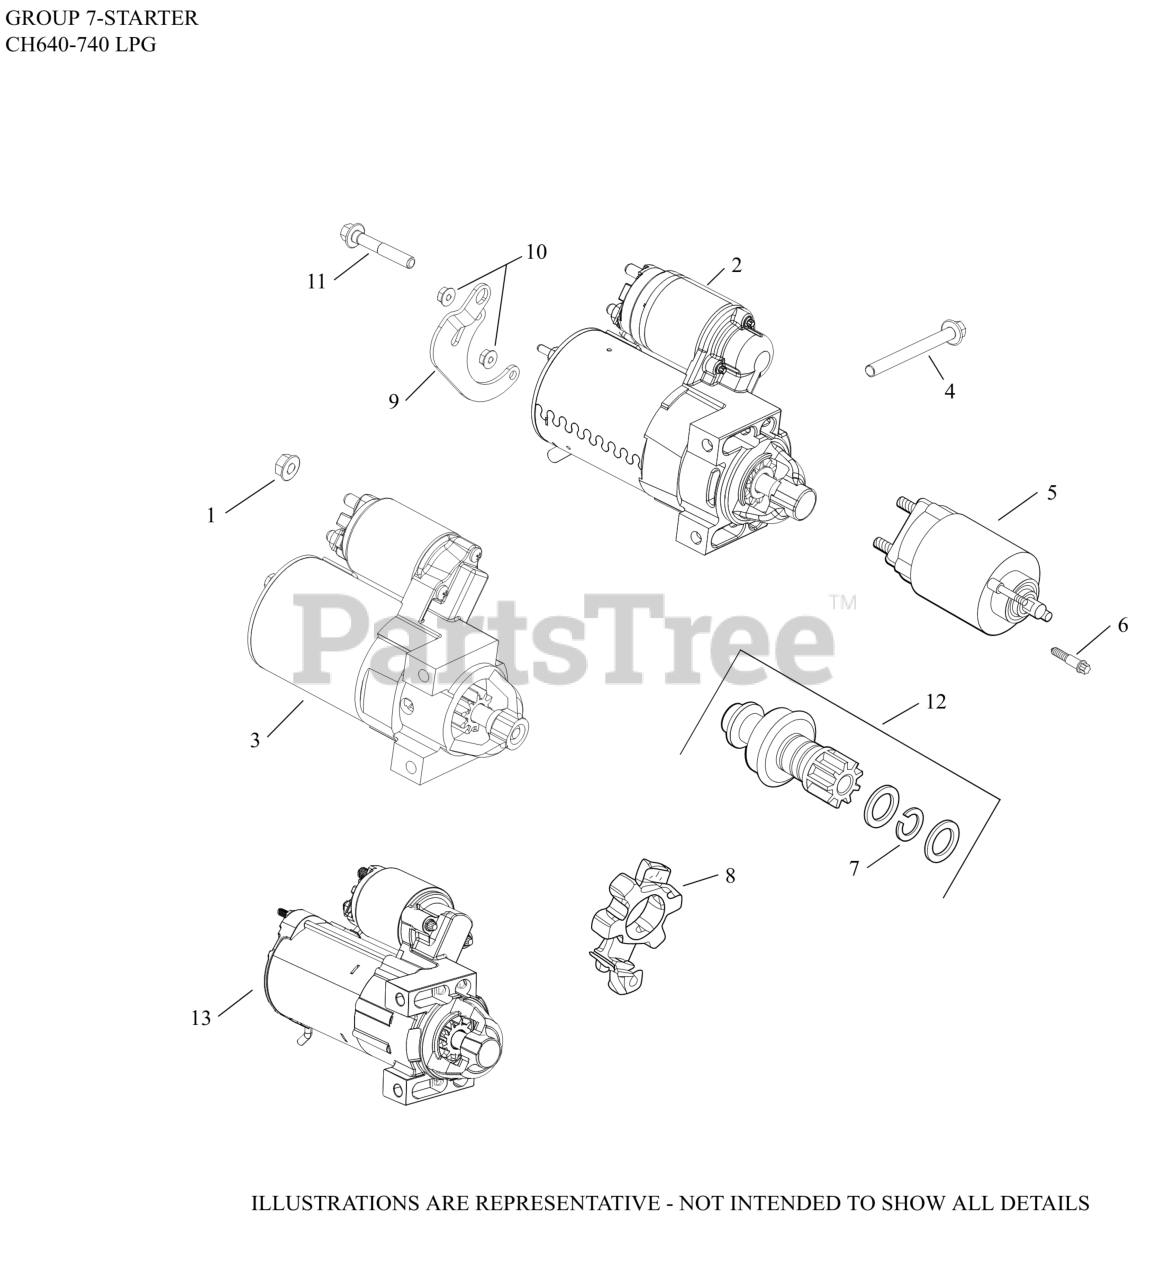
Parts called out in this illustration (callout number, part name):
1	NUT, FLG M8X1.25
2	STARTER, SOLENOID SHIFT-(#2509824S)
4	SCREW, FLG M8X1.25X80
